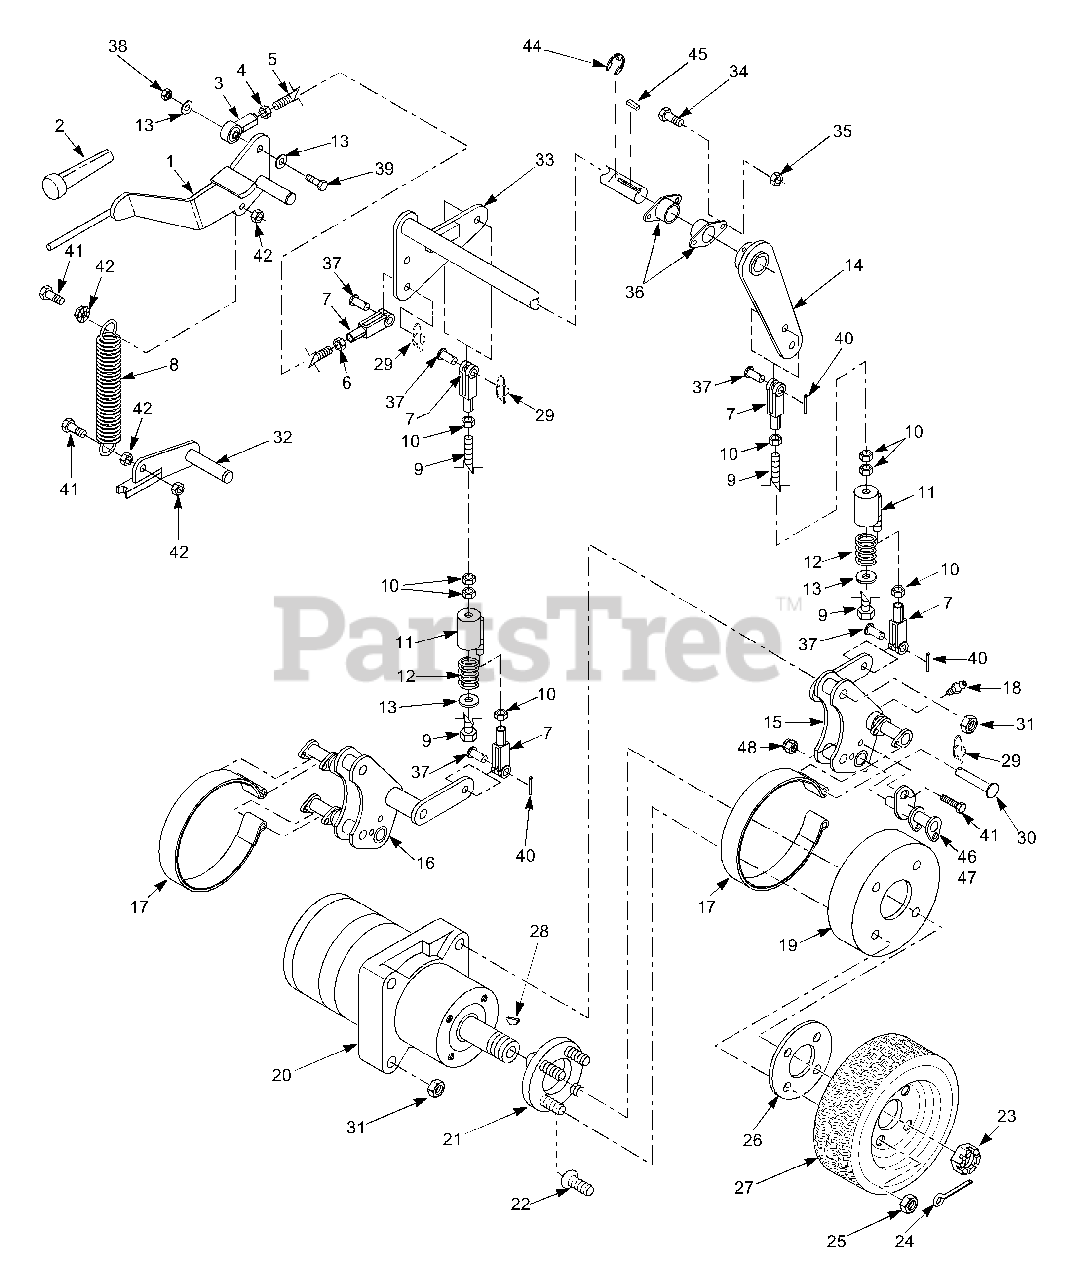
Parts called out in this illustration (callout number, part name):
1	Lever, Parking Brake
2	Grip, Parking Brake Lever
3	Rod End, 3/8-24 LH
4	Nut, 3/8-24 LH Thread
5	Rod, 3/8-24 x 9.5"
6	Nut, 3/8-24 RH Thread
7	Clevis, 3/8-24
8	Spring
9	Bolt, Hex Head 3/8-24 x 8.25"
10	Nut, 3/8-24
11	Weldment, Brake Rod
12	Spring
13	Flatwasher, 3/8"
14	Weldment, Brake
15	Weldment, Brake Linkage
16	Weldment, Brake Linkage
17	Band, Brake
18	Fitting, Grease
19	Drum, Brake
20	Motor, Hydraulic Wheel
21	Hub, Wheel
22	Stud, Wheel Mounting 1/2-20
23	Nut, Castle 1.0-20 UNF
24	Pin, Cotter 9/16" x 1.5"
25	Nut, Lug 1/2-20
26	Spacer, Wheel
27	Wheel Assy 23 x 9.50-12
28	Key, Woodruff 5/16 x 1"
29	Pin, Rue Cotter 3/8" Diameter
30	Pin, Clevis 3/8" Diameter x 2"
31	Locknut, Hex 1/2-13 Center Lock
32	Weldment, Deck Stop
33	Weldment, Brake Shaft
34	Bolt, Hex Head 5/16-18 x .75"
35	Nut, Elastic Stop 5/16-18
36	Bushing, Self-Aligning
37	Pin, Clevis 3/8 x 1.06"
38	Nut, Elastic Stop 3/8-16
39	Bolt, Hex Head 3/8-16 x 1.5"
40	Pin, Cotter 3/32 x .75"
41	Bolt, Hex Head 5/16-18 x 1"
42	Nut, Serrated Flange 5/16-18
44	E-Clip, .875"
45	Key, 1/4 x 1/4 x 1"
46	Brake Linkage Weldment, LH
47	Brake Linkage Weldment, RH
48	Nut, Elastic Stop 5/16-18
